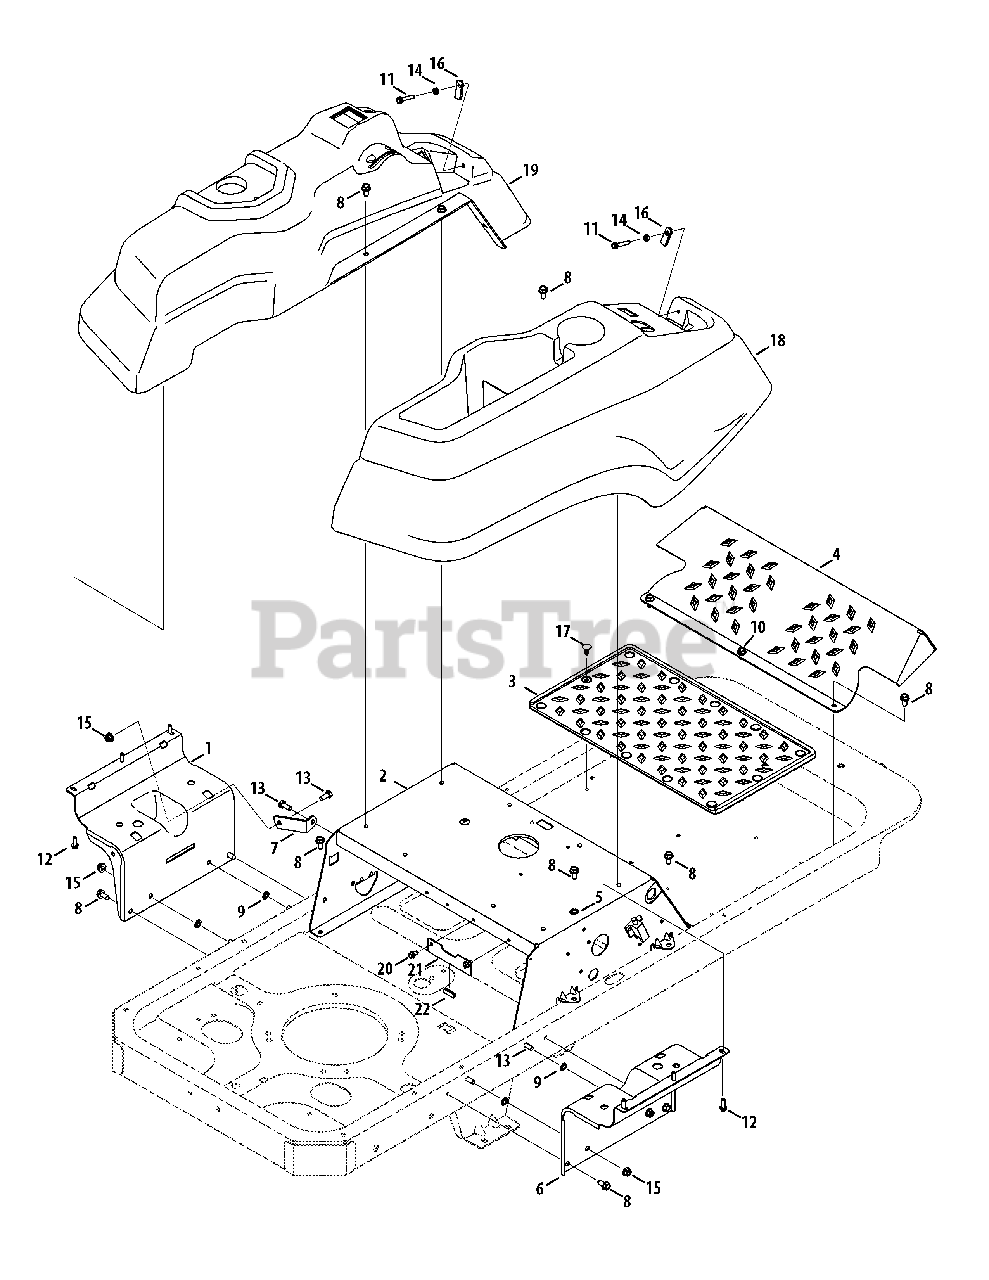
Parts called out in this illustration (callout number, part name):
3	Foot Pad
8	Hex Washer Screw, 5/16-18 x .750
9	Speed Nut, .3125
10	Hex Washer Screw, 5/16-18 x .825
11	Hex Washer Screw, 1/4-20 x 1.500
12	Hex Washer Screw, 1/4-15 x .750
13	Hex Screw, 5/16-18 x .75
14	Jam Nut, 1/4-20
15	Flange Lock Nut, 5/16-18
16	U-Type Nut, 1/4-20
17	Ratchet Clip, .250
18	RH Console
19	LH Console
20	Hex Screw, 1/4-20 x .5
21	Battery Hold-Down
22	Trim Strip
